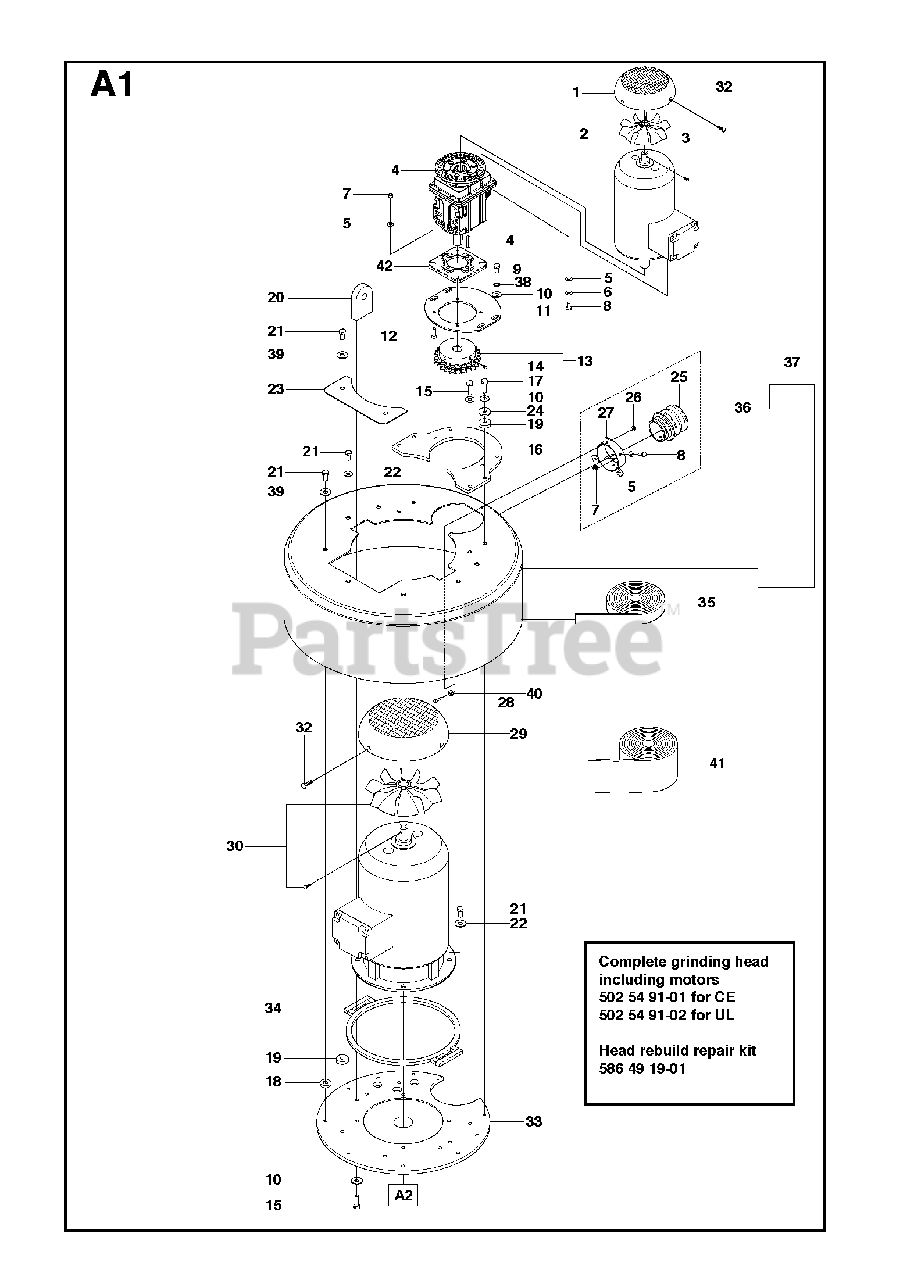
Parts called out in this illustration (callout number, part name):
5	WASHER
6	SPRING WASHER
7	HEXAGON LOCKING NUT
10	WASHER
22	WASHER
26	HEXAGON LOCKING NUT
28	SCREW CRCSFM
